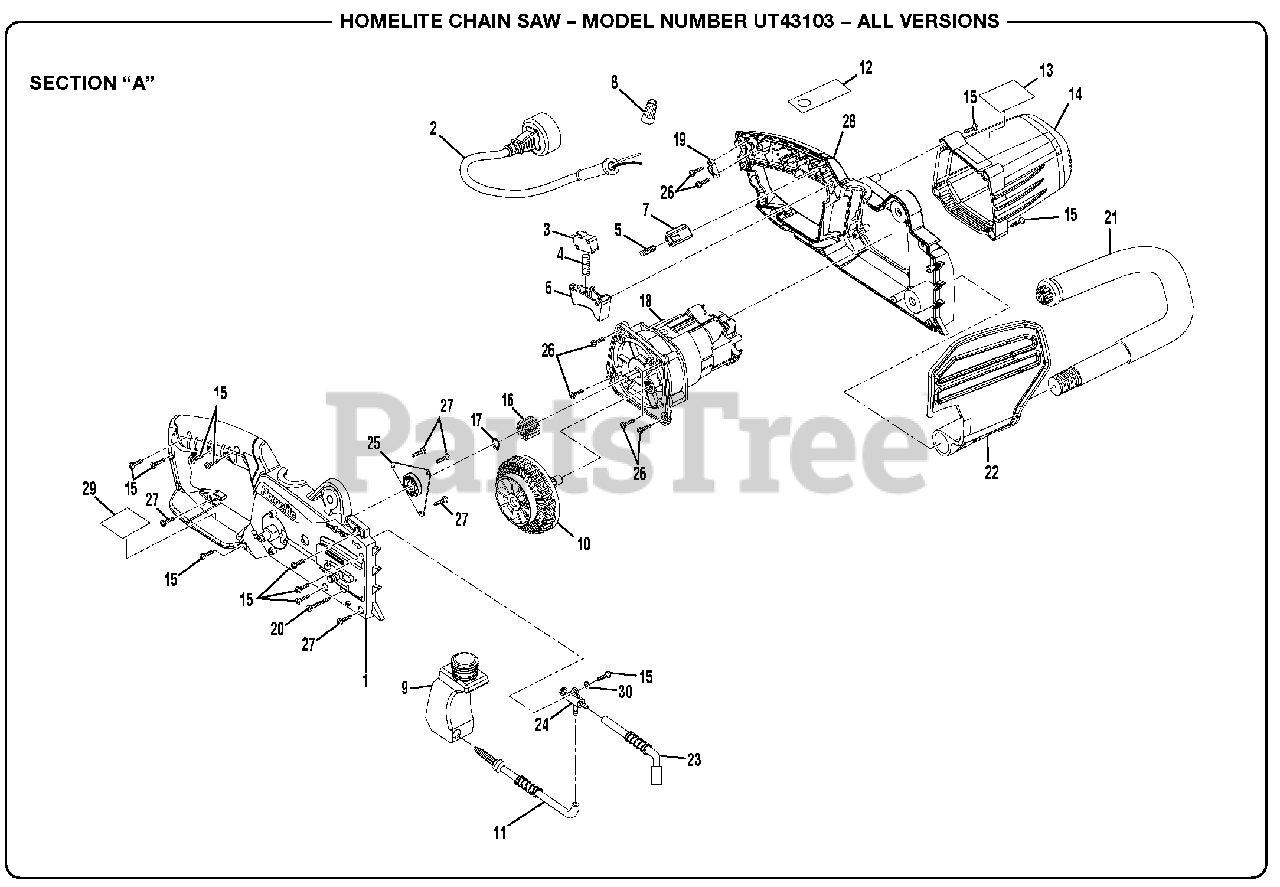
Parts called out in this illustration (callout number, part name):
1	Right Housing
2	Power Cord
4	Trigger Spring
5	Lock-off Spring
7	Lock-off Button
9	Oil Reservoir Assembly
10	Ring Gear Assembly
11	Oil Tube, Inlet
13	Data and Warning Label
14	Motor Cover
15	Screw (M4.2 x 14 mm)
17	Retaining Ring
18	Motor Assembly
19	Cord Clamp
20	Screw (M4 x 30 mm)
21	Front Handle
23	Oil Tube, Outlet
25	Ball Bearing Holder Assembly
26	Screw (M4.2 x 10 mm)
27	Screw (M4 x 8 mm)
28	Left Housing Assembly
30	Washer (M4)
